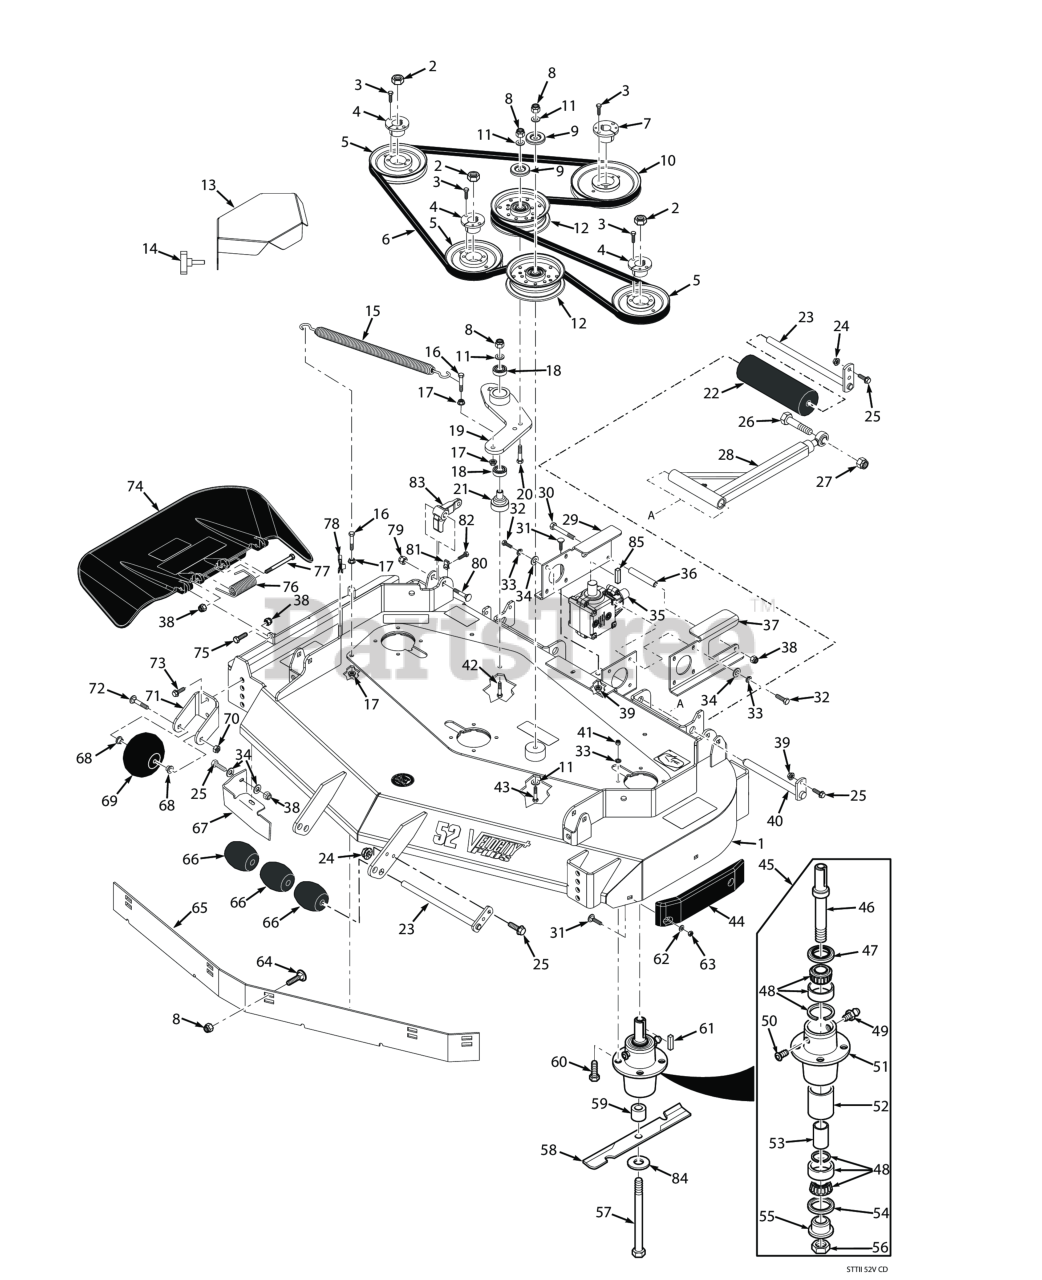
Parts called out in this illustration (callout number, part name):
1	Cutter Deck w/Decals - 52V
2	Hex Locknut, Elastic Stop, 3/8-16
3	Bolt, Hex Head 1/4-20 x 1" Grade 8 Black
4	Hub, Tapered 1-1/8" Bore
5	Pulley, 5.75 O.D. (Gasoline Engines)
6	Belt, Cutter Deck Drive
7	TAPERED HUB, 1.00" BORE
8	HEX NUT, ELASTIC STOP LOCK, 3/8-16
9	Quick Pin, 5/16" Dia.
10	Pulley, 6.95" O.D. - 72"
11	Flatwasher, 3/8 (.391 x .938 x .105 HD) Grade 8
12	Idler Pulley, Belt Clutch
13	Belt Cover LH
14	Knob, w/stud 3/8-16 x 1-1/4"
15	Spring, Cutter Deck
16	Bolt, Hex Head 3/8-16 x 1-1/2" Grade 8 Black
17	NUT, 3/8-16 SERRATED FLANGE HEX HEAD
18	BEARINGS, BALL, NEUTRAL RETURN
19	Idler Arm, Cutter Deck
20	Capscrew, Hex Head 3/8-16 x 2.75"
21	Pivot, Idler - Short
22	Wheel, Anti-ScalpRelief Fitting, Tapered Spindle
23	Shaft Weldment, Guide Roller
24	Nut, Flange Head Elastic Stop 5/16-18
25	Bolt, Heax Head 5/16-18 x 1" (48V / 52V)
26	BOLT, HEX HEAD 5/8-11 X 4-1/2"
27	HEX LOCKNUT, ELASTIC STOP, 5/8-11
28	Push Arm (Includes 64,60,62)
29	Mounting Plate
30	Bolt, 5/16-18 x 4-3/4" Hex Head
31	Bolt, 5/16-18 x .75 RHSN Carriage
32	Bolt, Heax Head 5/16-18 x 1" (48V / 52V)
33	Lockwasher, 5/16 (.317 x .586 x .078) Helical Spring
34	Flatwasher, 5/16-.375 x .875 x .083 (35BV & 37BV-EFI)
35	Gearbox Assembly, Deck Drive
36	Spacer, Gearbox Mount
37	Mounting Plate
38	HEX NUT, ELASTIC STOP LOCK, 5/16-18
39	Nut, Serrated Flange 5/16-18 (Right Front Engine Mounting, Briggs and Kohler Only)
40	Shaft Weldment, Pusharm
41	Lock Nut, 5/16-18 Elastic Stop Grade 8
42	Bolt, Hex Head 3/8-16 x 3" - 52"
43	Capscrew, Hex Head 3/8-16 x 3-3/4"
44	Pad, Deck Wear
45	Cutter Spindle Assembly
46	Spindle Shaft, Tapered Brng
47	SEAL, 2.00 O.D. X 1.50 BORE
48	Tapered Bearing Set (Two Bearings W/Race)
49	GREASE FITTING, STR. 1/4-28 SELF TAP.
50	RELIEF FITTING, TAPERED BEARING SPINDLE
51	Housing, Spindle
52	Spacer, Outside, Cutter Spindle
53	SLEEVE, CUTTER SPINDLE
54	Seal, 2.00" O.D. x 1.625" Bore
55	SPINDLE BUSHING, BOTTOM
56	Nut , Spec ial 1 -1/ 1 6 - 1 8
57	BOLT, HEX HEAD, 5/8-11 X 9-1/2 GR.5
58	Cutter Blade, 18" (52V)
59	Spacer, Spindle Bottom
60	Bolt, Hex Head 5/16-18 x 1-3/4" Grade 8
61	Key, 1/4 x 1/4 x 2.0"
62	Flatwasher, 5/16-.344 x .688 x .065 (48V / 52V)
63	Nut, Center Lock, 5/16-18(32)
64	Carriage Bolt, 3/8-16 x 1.0"
65	Baffle Custom-Cut, 52V (7-Position)
66	Wheel, Anti-Scalp
67	Turbo Baffle - 48V / 52V
68	Bushing, .376" I.D. Oilite
69	Bolt, Carriage 3/8-16 x 4"
70	Bolt, Hex Head 3/8-16 x 1" Ser. Flg.
71	Bracket, Anti-Scalp Wheel
72	Bolt, Hex Head 3/8-16 x 3-1/2"
73	Capscrew, 3/8-16 x 1.0" Serrated Flange Hex Hd
74	Discharge Chute Assembly - 52V
75	Bolt, Hex Head 5/16-18 x 1-1/2" - Front
76	Spring, Discharge Chute
77	Bolt, 5/16-18 x 4-3/4" Hex Head
78	U-Nut, 3/8-16
79	HEX LOCKNUT, ELASTIC STOP, 7/16-14
80	Bolt, Carriage 7/16-14 x 2-1/4"
81	U-Nut, 3/8-16 (short)
82	Bolt, Hex Head 3/8-16 x 2" Special Lock
83	Lever, Deck Level
84	Flatwasher, 5/8-.688 x 1-3/4 x .134 HD
85	Key, 1/4 x 1/4 x 1.25" Pulley Mtg.
